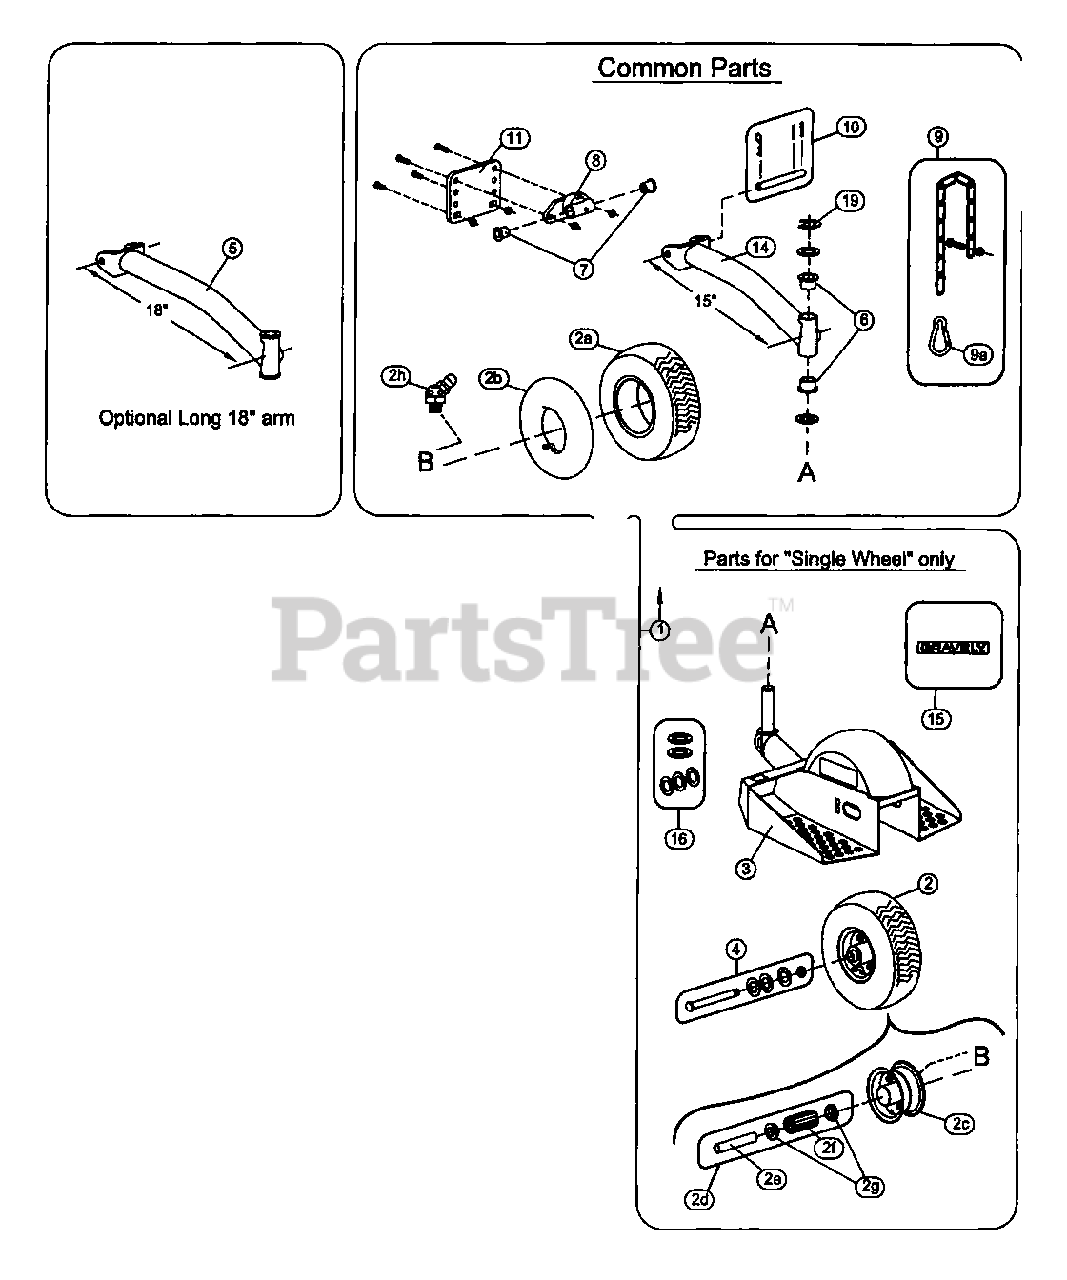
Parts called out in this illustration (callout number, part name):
1	SULKY, Single Wheel w/15" arm
2	Wheel Assy., w/centered hub & spanner
3	Foot Platform, Single Wheel (w/decals)
4	Axle Bolt (w/spacers and self locking nut)
5	Arm, 18" (w/bushings & grease fitting)
6	Bronze Bushing pivot(s)
7	Bronze Bushing for hitch
8	Hitch (w/bushings & grease fitting)
9	Snap & Chain Kit
10	Clevis pin
11	Adapter plate
14	SHORT 15" arm (w/bushings)
15	Gravely Logo Decal
16	Spacer kit
19	E Clip 7/8"
